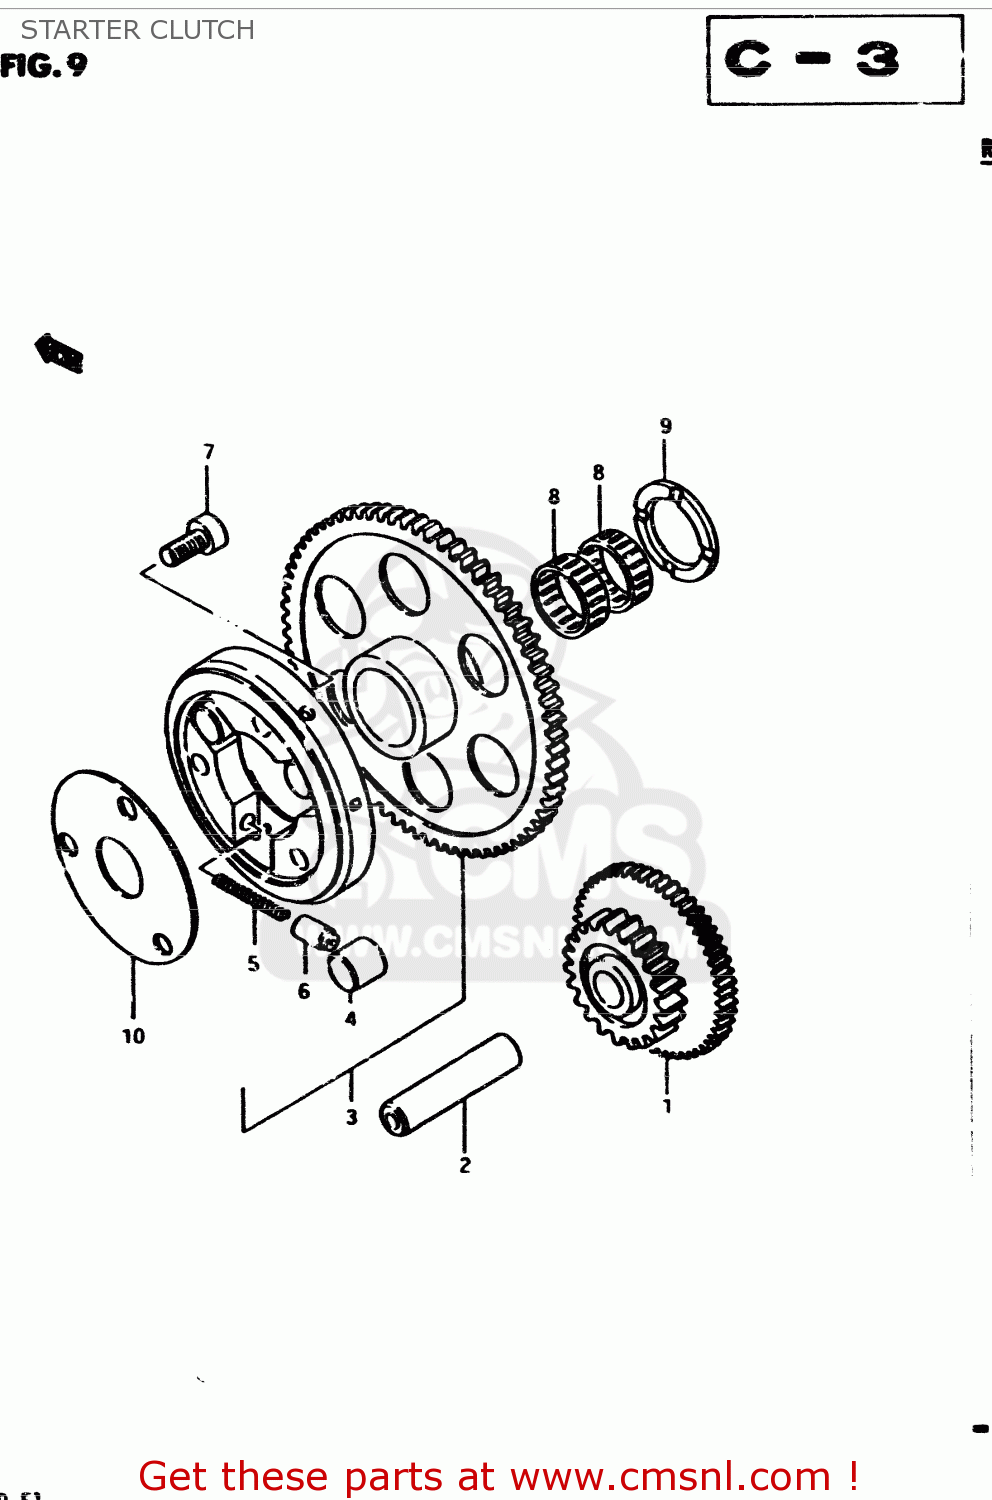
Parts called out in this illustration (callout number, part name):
1	GEAR,STARTER IDLE
2	PIN(7.4X13X61)
3	CLUTCH SET,STARTER
4	ROLLER(15X13)
5	SPRING
6	PIECE,PUSH
7	BOLT
8	BEARING(25X29X9.9)
9	WASHER(25X38X2.5)
10	SHIM,STARTER CLUTCH HUB
